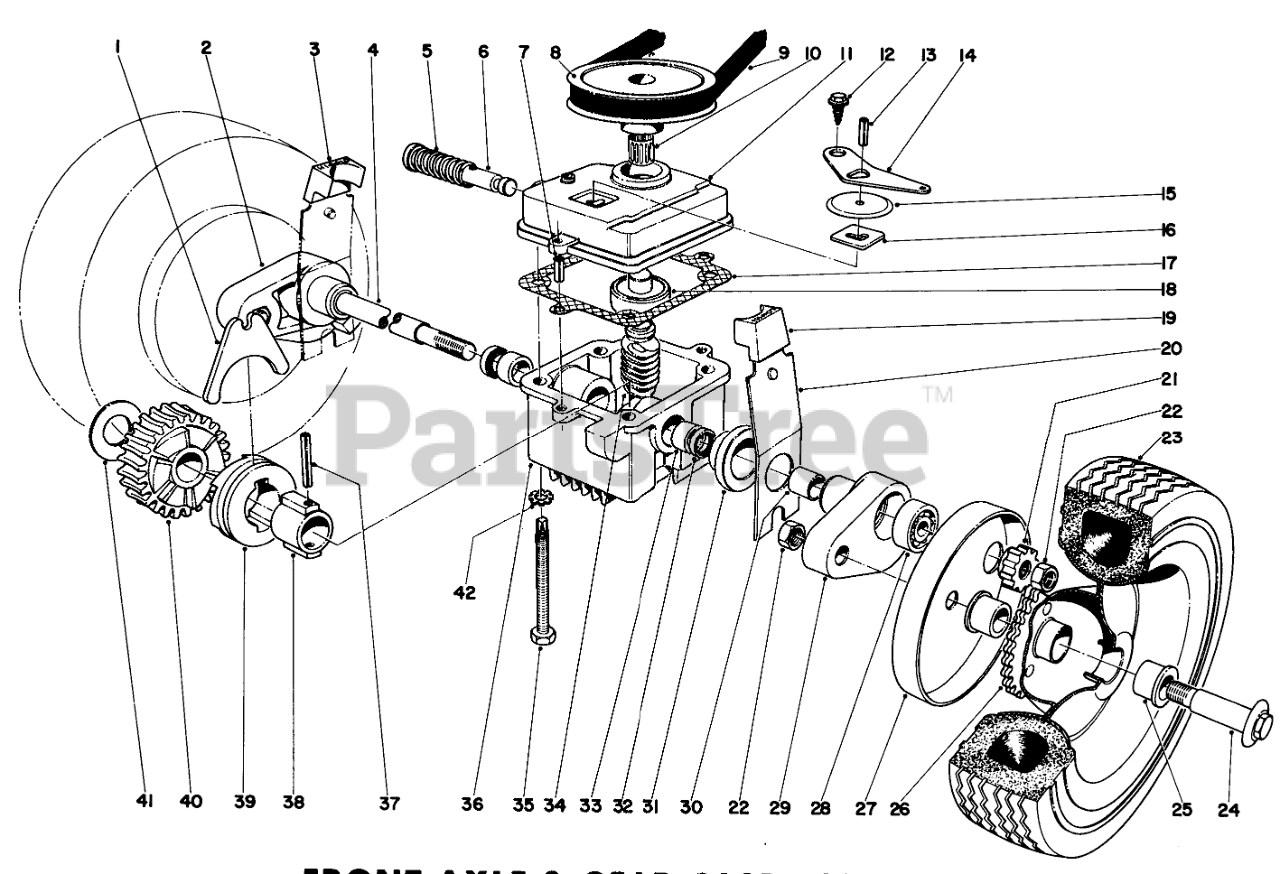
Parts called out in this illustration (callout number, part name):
1	SHIFTER FORK
2	Pivot Arm (Incl. Ref. 30)
4	DRIVE SHAFT
5	SPRING
6	Shift Rod
7	3/16 X 1/2 ROLL PIN
8	PULLEY
9	V BELT
10	TOLERANCE RING
11	GEAR CASE COVER
12	Screw
13	PIN-ROLL
14	SHIFTER ARM
15	TRANS DUST COVER
16	LATCH PLATE
17	GASKET
18	Bearing
19	ARM KNOB
20	Spring Arm
21	PINION GEAR
22	Nut
23	8 TIRE
24	Wheel Bolt
25	FLANGE BUSHING
26	Wheel Assembly
27	WHEEL COVER
28	.375 RPP BALL BEARING
29	Pivot Arm (Incl. Ref. 30)
30	BUSHING
31	End Cap
32	Seal
33	Bushing
34	Worm Shaft
35	Sems Screw
36	Gear Case
37	PIN-SPRING
38	SLEEVE
39	Clutch
40	Worm Gear
41	THRUST WASHER
42	WASHER-LOCK/EXT
